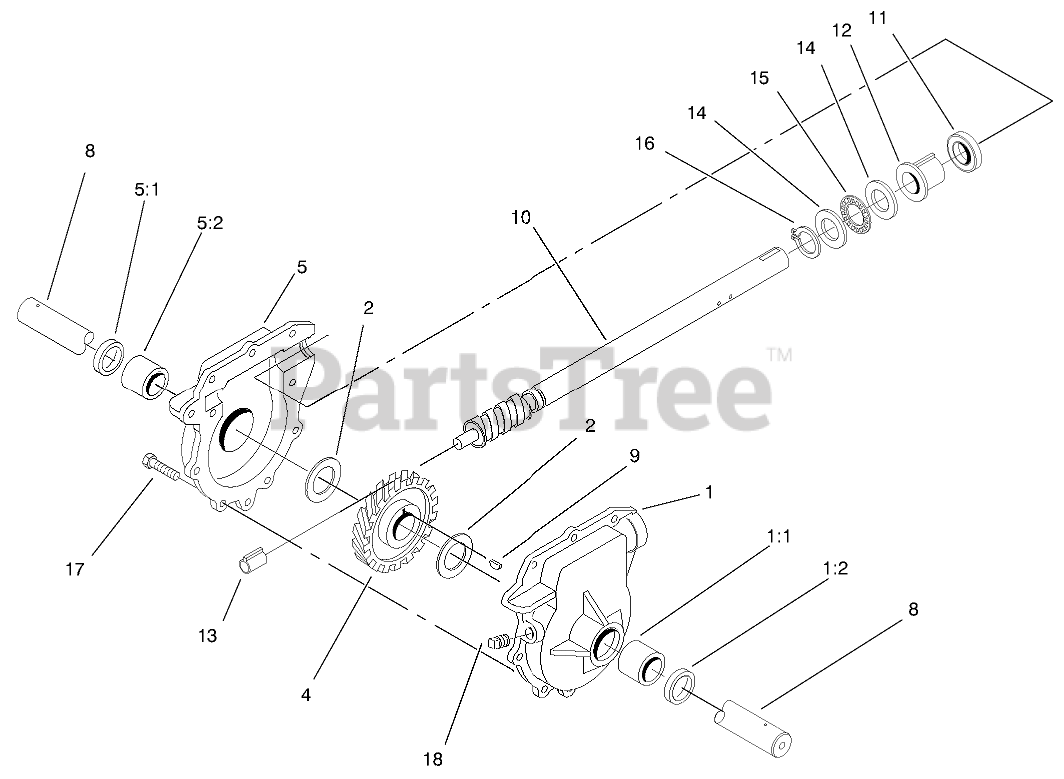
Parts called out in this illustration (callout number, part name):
1	LH AUGER GEARCASE ASM
1:1	BUSHING
1:2	SEAL-OIL
2	WASHER-THRUST
4	GEAR-HELICAL
5	RH AUGER GEARCASE ASM
5:1	SEAL-OIL
5:2	BUSHING
8	SHAFT-AUGER
9	KEY-WOODRUFF
10	Shaft-Impeller
10	SHAFT-IMPELLER
11	SEAL-OIL
12	BUSHING-INPUT
13	BUSHING-WORM
14	WASHER-THRUST
15	BEARING-THRUST
16	RING-RETAINING, Ext
17	SCREW-HWH
18	PLUG-PIPE, SQH
